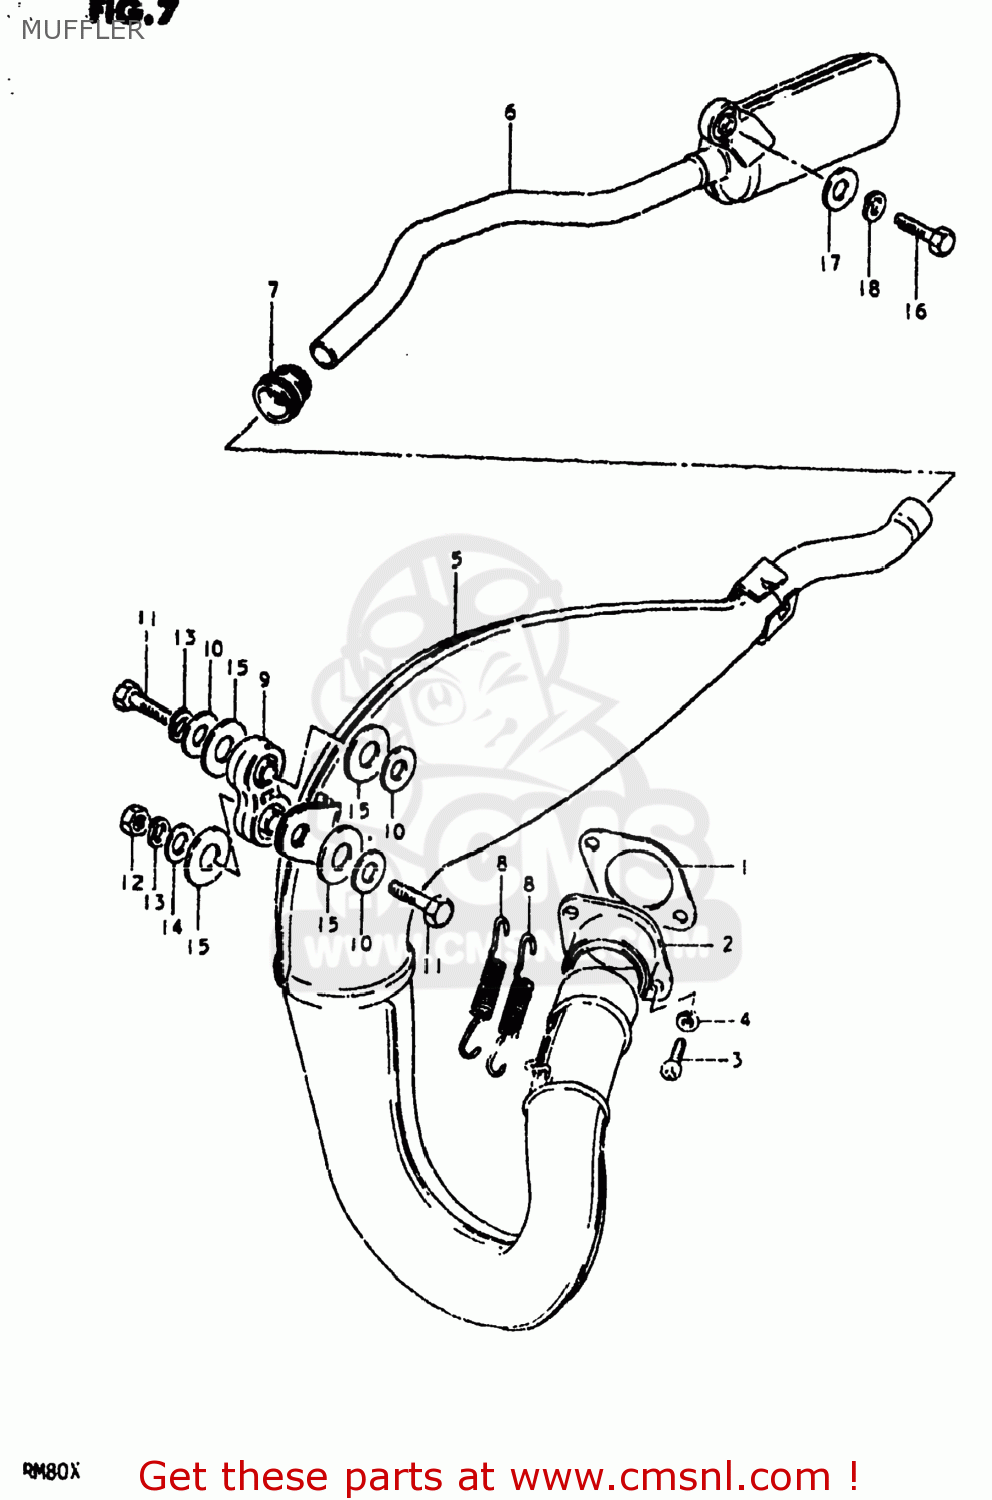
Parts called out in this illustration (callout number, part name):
1	GASKET,EXHAUST PIPE (MCA)
2	PIPE,CENTER EXHAUST
3	SCREW
4	LOCK WASHER
5	BODY,MUFFLER
6	BODY,MUFFLER
7	CONNECTOR,MUFFLER
8	SPRING
9	DAMPER,MUFFLER
10	WASHER
11	BOLT
12	NUT
13	LOCK WASHER
14	WASHER
15	WASHER(13X28X1.6)
16	BOLT
17	WASHER
18	LOCK WASHER
